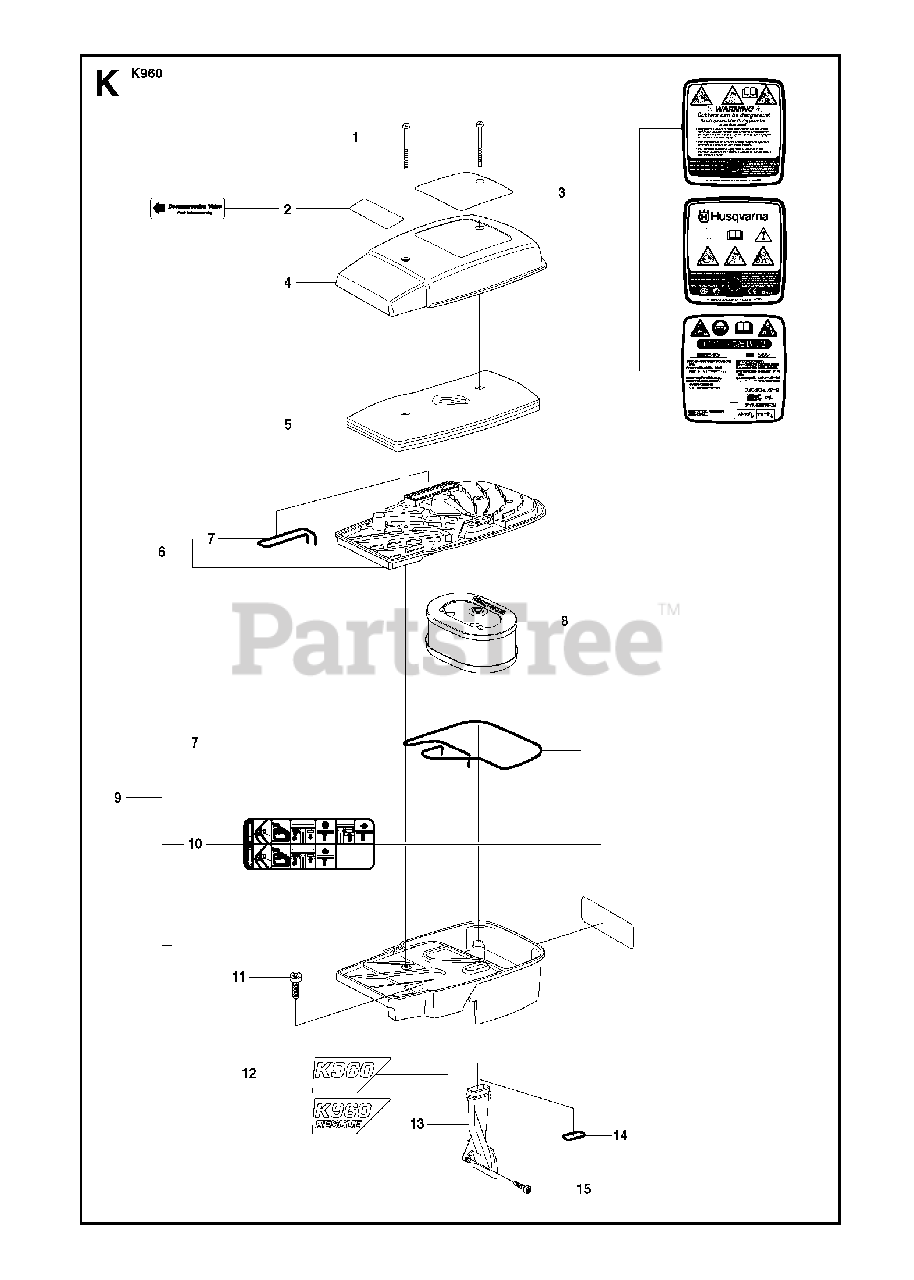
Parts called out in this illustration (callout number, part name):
1	SCREW ITXSCM
3	LABELEPA USA
3	LABEL
4	COVER
6	FILTER BOTTOMIncl. 7
9	CYLINDER COVER ASSYIncl. 7, 10
11	SCREW ITXSCM
15	SCREW ITXSCM
